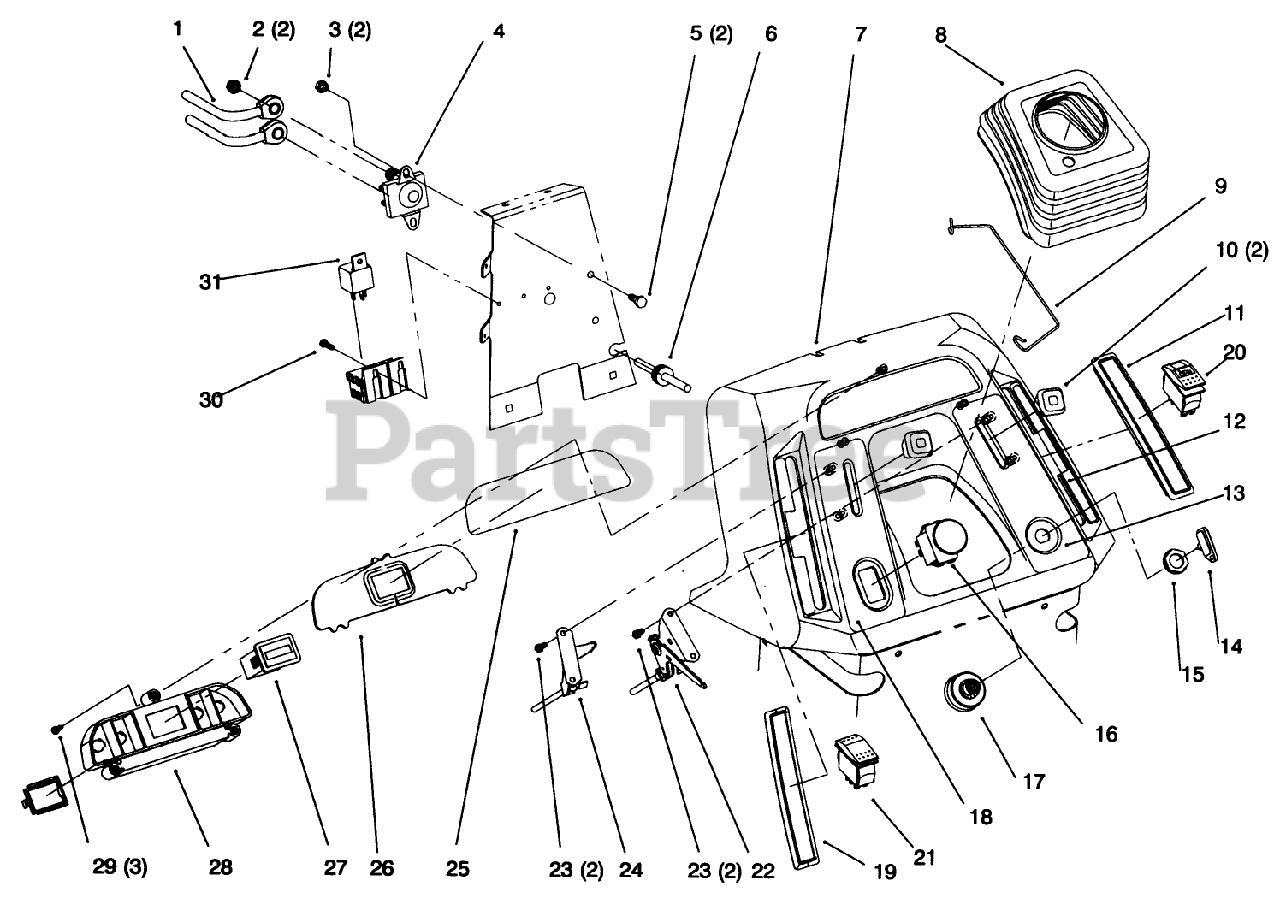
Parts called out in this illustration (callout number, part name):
1	WIRE-21 INCH
2	NUT-KEPS
3	NUT-LOCK, NI
5	SCREW-HH
6	GROMMET-RUBBER
8	BOOT-STEERING
9	CLIP-BOOT
11	COVER-SLOT, RH
13	DECAL-THROTTLE, IGNITION
13	DECAL-DASH
14	KEY-IGNITION
16	SWITCH-PTO,ON-ON-NONE
17	SWITCH-IGNITION
18	DECAL-PTO / CHOKE
18	DECAL-DASH, PTO/CHOKE
19	COVER-SLOT, LH
22	CONTROL-THROTTLE
24	CONTROL-CHOKE
25	DECAL - DASH LENS
26	LENS-DASH
27	HOURMETER
28	HOUSING-LIGHT, INDICATOR
29	SCREW-PPH
30	SCREW-PPHTF
31	RELAY
